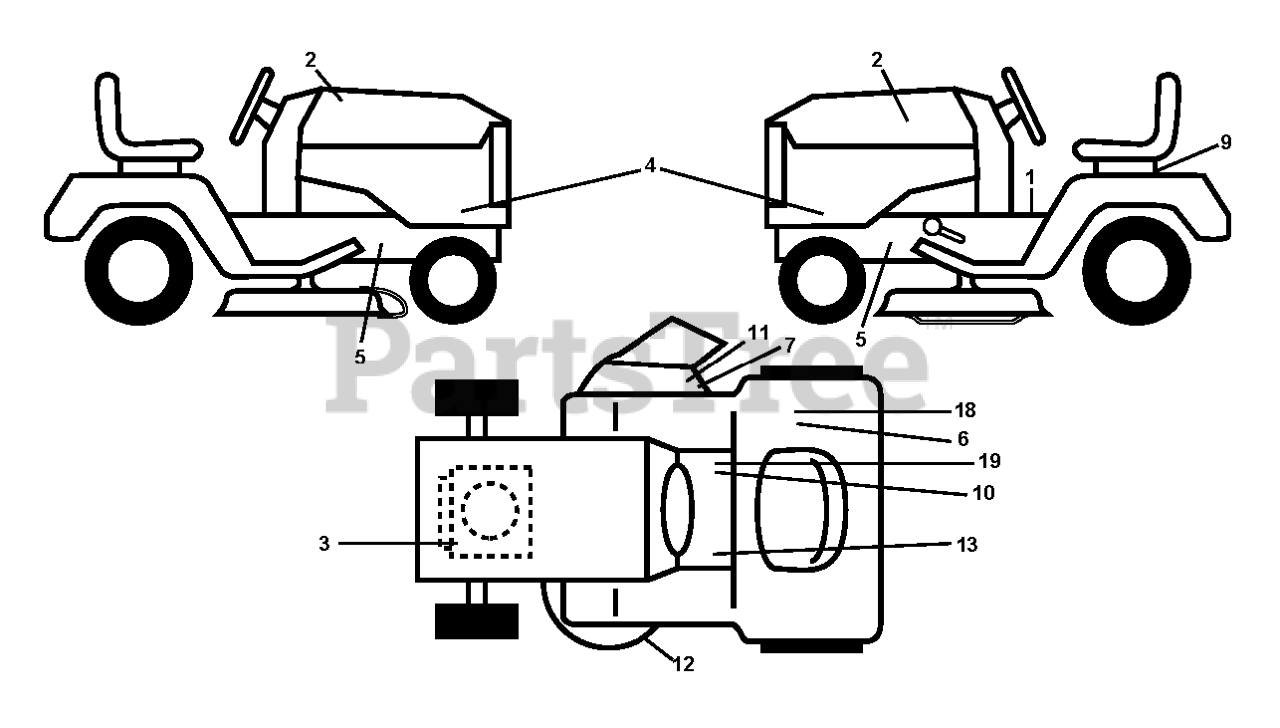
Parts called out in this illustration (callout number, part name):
1	LABEL
2	DECAL.HOOD.LOGO.ORANGE.HUSQVAR
3	DECAL
6	DECAL 80 DBA
7	DECAL, DEFLECT WARNING
9	DECAL BTRY SYMBOLS
10	DECAL PARK BRAKE
11	DECAL.INTERNATIONL.CUTFINGER
12	DECAL.V-BELT.SCHEMATIC.36/38/9
13	DECAL
18	DECAL
19	DECAL
